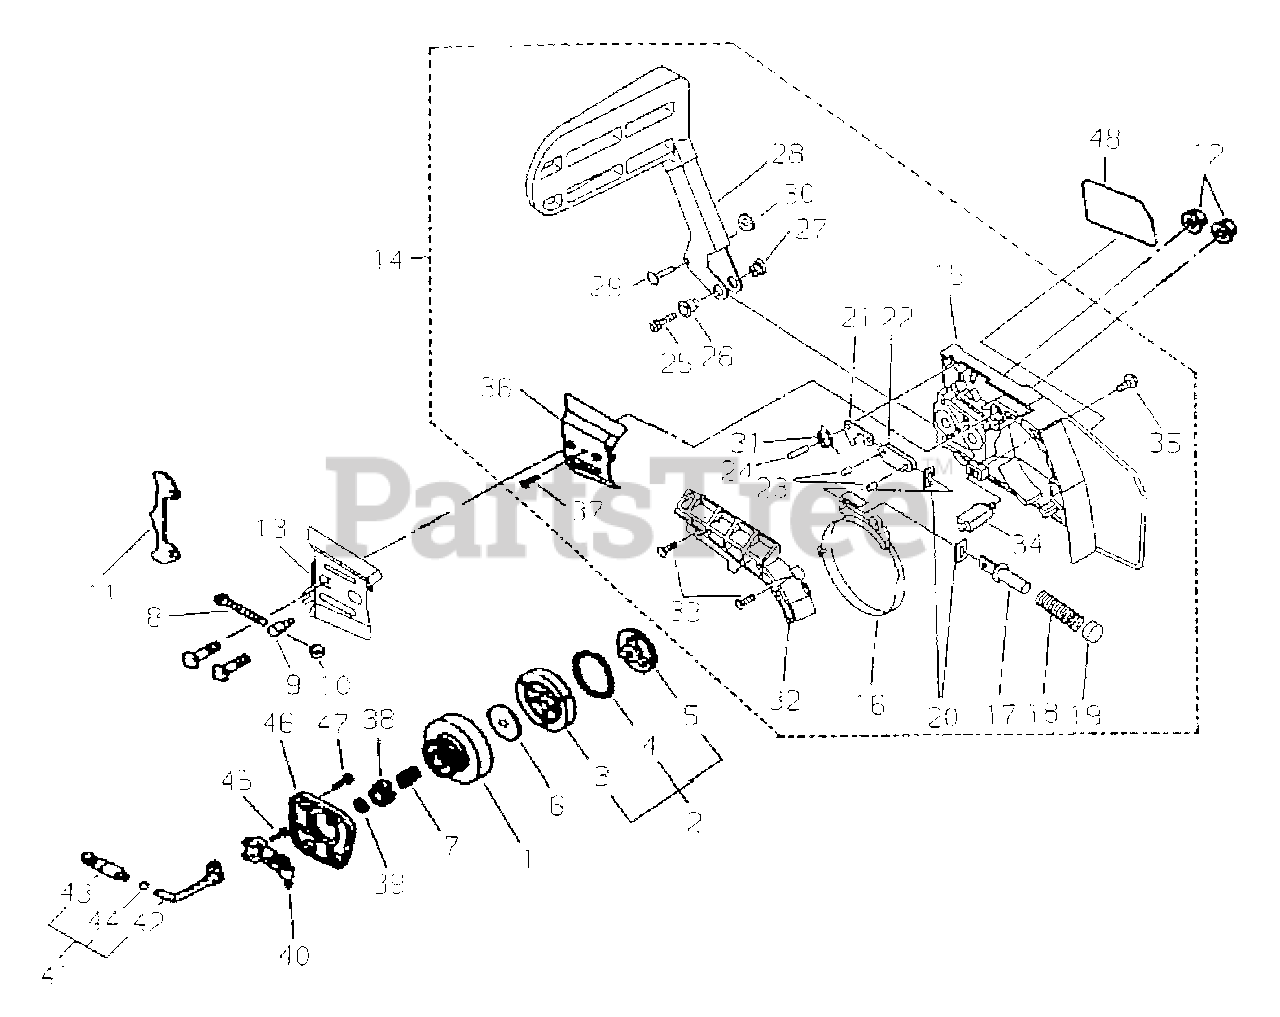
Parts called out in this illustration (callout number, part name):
1	DRUM, CLUTCH
2	CLUTCH ASSY
3	SHOE, CLUTCH
4	SPRING, CLUTCH
5	HUB, CLUTCH - OUTER
6	HUB, CLUTCH - INNER
7	BEARING, NEEDLE
8	SCREW, ADJUST
9	TENSIONER, CHAIN
10	NUT
11	SPIKE
12	NUT, GUIDE BAR
13	PLATE, GUIDE
14	CLUTCH COVER ASSY
15	COVER, CLUTCH
16	BAND, BRAKE
17	HOLDER, SPRING
18	SPRING, BRAKE
19	STOPPER
20	ADJUST PLATE
21	LEVER - INNER
22	TIE, CABLE
23	PIN - LOCATING
24	PIN - LOCATING
25	SCREW - 4X12
27	NUT
28	LEVER
30	NUT
31	LEVER, SPRING
32	COVER
33	SCREW - 4X12 -- TAPPING
34	CATCHER, CHAIN
35	SCREW - 3X10
36	PLATE, GUIDE - OUTER
37	SCREW - 4X8 -- TAPPING
38	GEAR
39	WASHER, THRUST
40	AUTO-OILER ASSY
41	OIL FILTER ASSY
42	PIPE - OIL
43	FILTER, OIL
44	CLIP
45	SCREW - 4X12
46	COVER, PUMP
47	SCREW - 4X12
48	LABEL - MODEL
